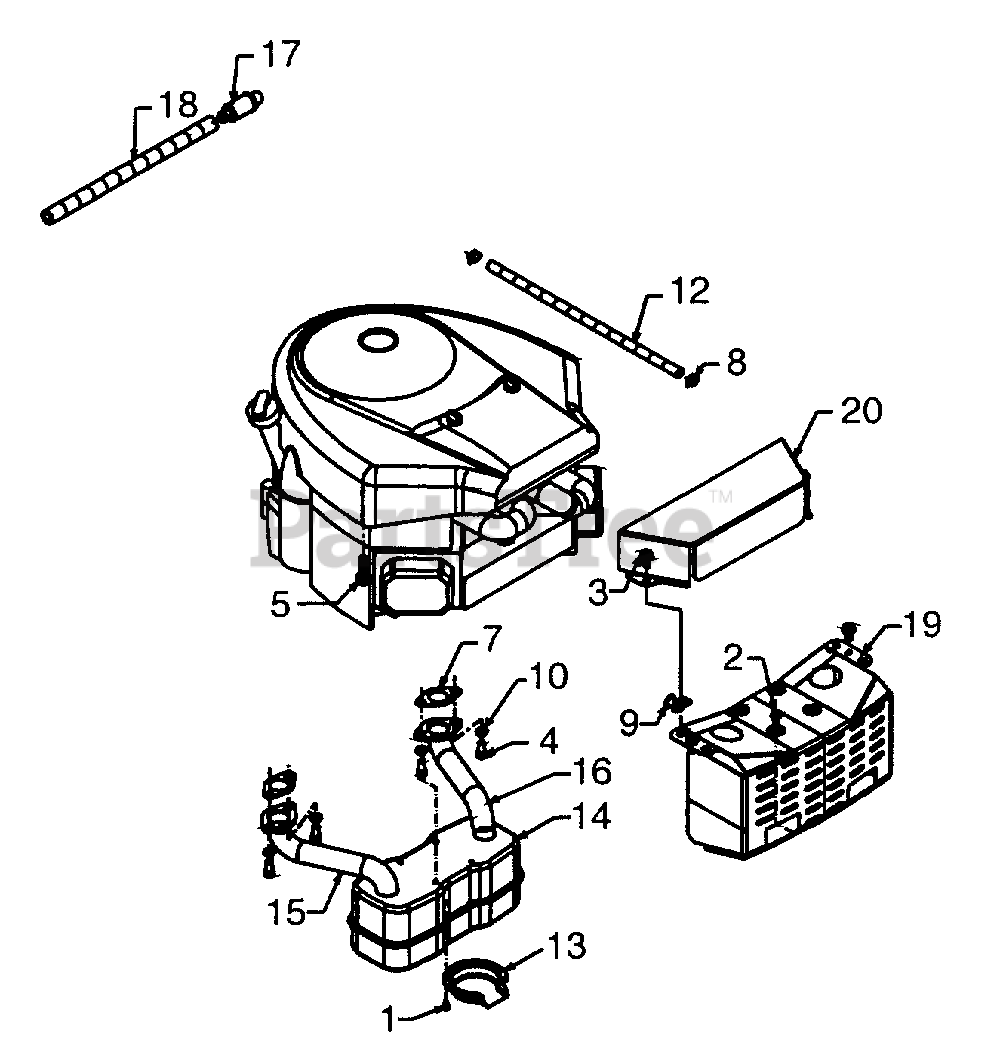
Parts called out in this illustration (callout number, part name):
1	Hex Tap Scr. #8-32 x .38" Lg.
2	Hex Wash. TT-Tap Scr. 1/4-20 x 5" Lg.
3	Hex Wash. TT-Tap Scr. 5/16-18 x .62"
4	Socket Head Scr. 5/16-18 x .62"
5	Hex TT-Tap Scr. 318-16 x 1.25"
7	Exhaust Gasket
8	Hose Clamp
9	Clamp
10	L-Wash. 5/16" I.D.
12	Fuel Line 12" Lg.
13	Muffler Deflector
14	Muffler
15	Exhaust Pipe-R.H.
16	Exhaust Pipe-L.H.
17	Oil Drain
18	Oil Drain Hose
20	Heat Shield
